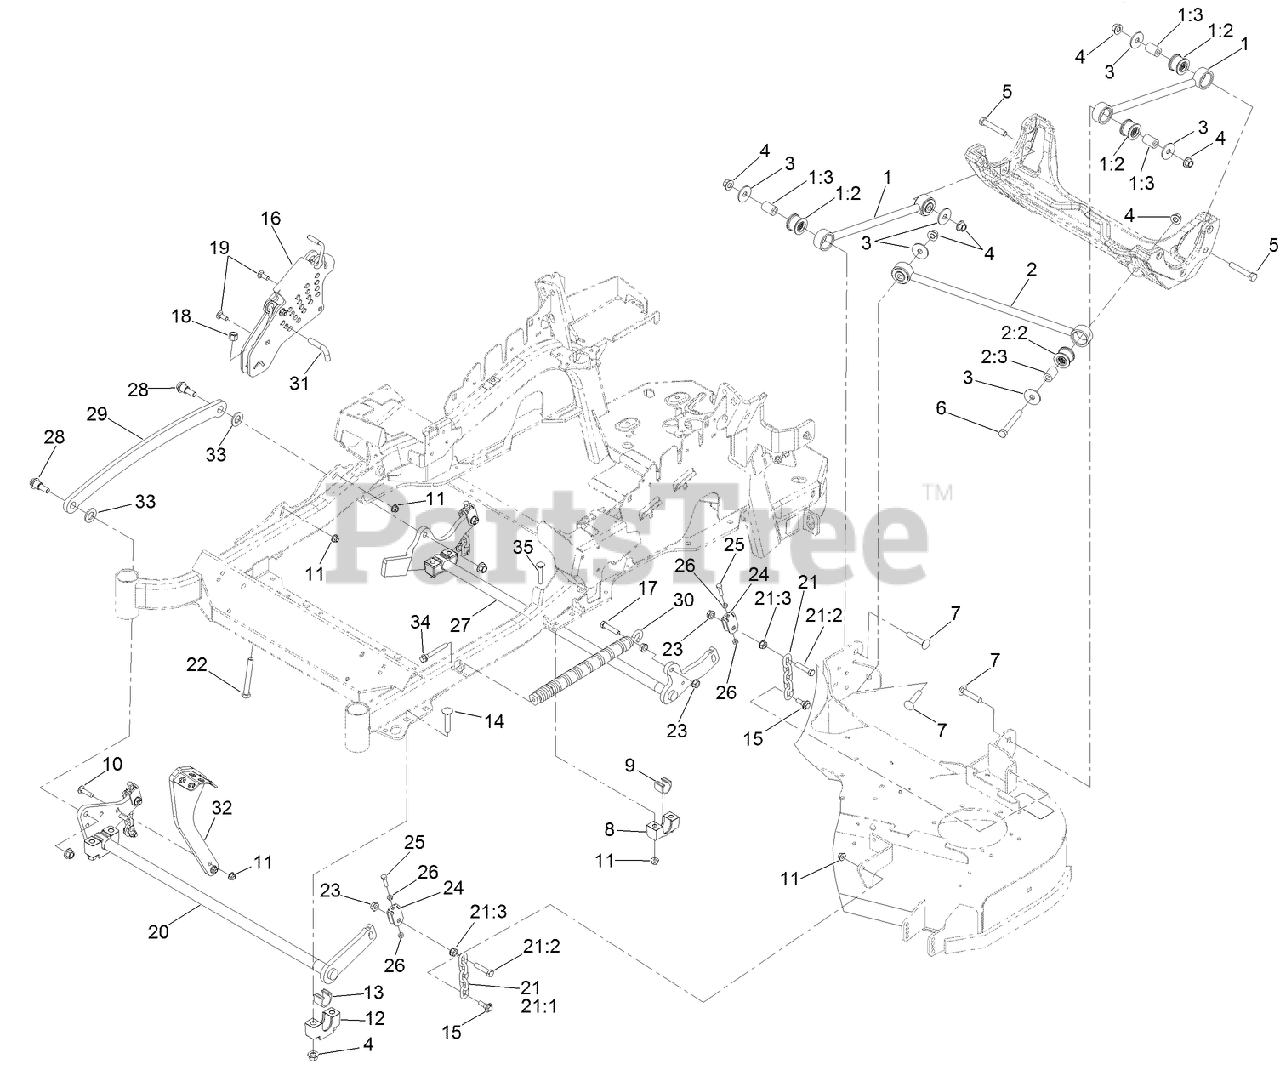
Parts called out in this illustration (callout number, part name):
1	DECK STRUT ASM
1:2	BUSHING-SUSPENSION, RUBBER
1:3	SPACER
2	PANHARD ROD ASM
2:2	BUSHING-SUSPENSION, RUBBER
2:3	SPACER
3	WASHER-THRUST
4	NUT-LOCK
5	SCREW-HH
6	SCREW-HH
7	SCREW-CARR
8	SUPPORT-CROSS SHAFT, BEARING REAR
9	BEARING-CROSS SHAFT, REAR
10	SCREW-HH
11	NUT-HF, NI
12	SUPPORT-CROSS SHAFT, BEARING
13	BEARING-CROSS SHAFT, FRONT
14	BOLT-CARR
15	SCREW-SHOULDER, HHF
16	HOC ASM
17	SCREW-HH
18	NUT-LOCK, NI
19	SCREW-HH
20	DECKLIFT-FRONT
21	DECK LIFT CHAIN ASM
21:1	CHAIN-LIFT, DECK
21:2	SCREW-HH
21:3	NUT-HF
22	BOLT-TAP
23	NUT-HF
24	YOKE-ADJUST, DECK
25	SCREW-HH
26	NUT-JAM
27	LIFT-DECK, REAR
28	SCREW-SHOULDER, HHF
29	LINK-LIFT, DECK
30	SPRING-EXTENSION
31	PIN-HOC
32	LEVER-FOOT
33	WASHER-FLAT
34	BOLT-SHOULDER
35	SCREW-HH
